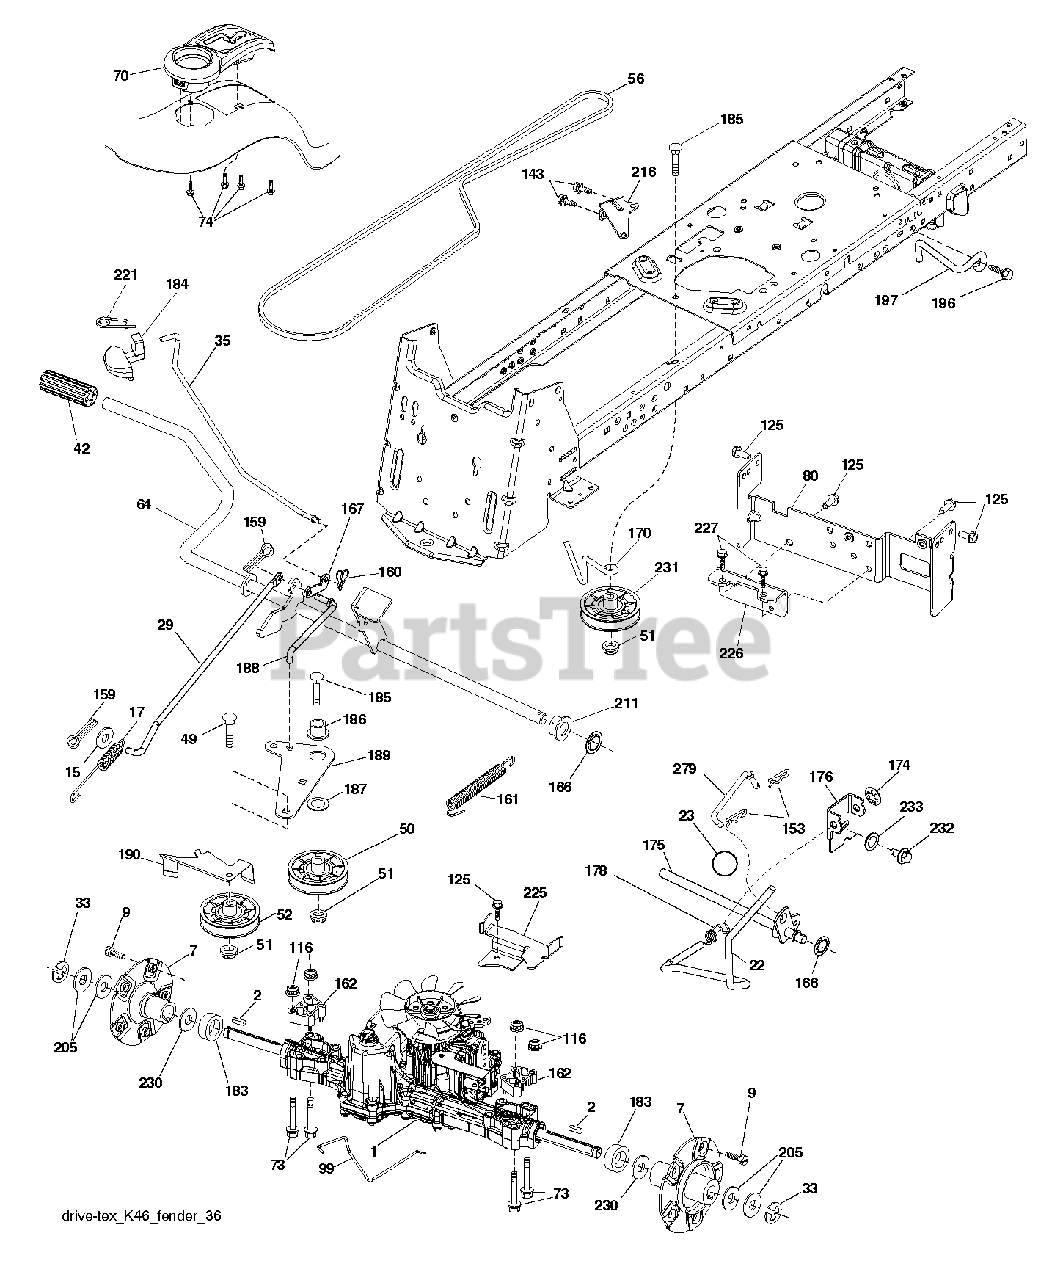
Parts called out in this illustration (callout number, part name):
2	KEY.SQUARE.187X2.500
7	HUB.ASM.WHEEL.REAR.22"
9	HUB BOLT
17	SPRING.BRAKE.K46.GREEN
22	ROD.SHIFT.FENDER.STGT.
23	KNOB.DELUXE.(PISTOL.GRIP).BLAC
29	ROD.BRAKE.K46
33	E-RING LT
35	ROD.BRAKE.PARKING.LT.T
49	BOLT
50	IDLER.FLAT.910.OFFSET
51	NUT LOCK FLG 3/8-16 UNC
52	IDLER.V-GROOVE.910.OFFSET
56	V-BELT.MOWER.92.40.42/K46
64	SHAFT.ASM.PEDAL.BRAKE.
70	PAD.FOOTREST.RH.STGT.BLACK
73	Hex Flange Bolt, 5/16-18 X 3.75
74	SCREW.HI-LO.CONSOLE
80	STRAP.TORQUE.K46.K57R.TT
99	ROD.SPRING.BYPASS.K46.TEX.GT
116	NUT LOCK HEX FLANGE 5/16-18
125	SCREW
143	SCREW LT
159	COTTER PIN
160	RETAINER CLIP
161	SPRING, RETURN LT
162	SPACER.TRANSAXLE.1"
166	NUT.PUSH.625
167	LATCH.BRAKE.SPRING
170	KEEPER.CENTER SPAN.1.688
174	NUT.PUSH.500.2006
175	SHAFT ASM SHIFT
176	ARM.CLEVIS.ROD.SHIFT
178	SPRING.SHIFT.GT2006
183	SPACER.SPLIT.800X.350
184	HANDLE.PARKING.BRAKE.LTTEX.667
186	SPACER.RETAINER
187	WASHER 12/32X2X10GA
188	LINK.CLUTCH.GROUND.DRIVE
189	BELLCRANK.GROUND.DRIVE.TEX.
190	KEEPER.BELLCRANK.DRIVE
196	SCREW 3/8-16X1
197	BRKT.ANIT-ROTATION.CLUTCH
211	BUSHING.SHAFT.BRAKE.HAND
216	BRACKET.PULLEY.IDLER.W/TEX
221	RETAINER.SPRING.CLIP.H
225	KEEPER.BELT.TRANSAXLE.K46
226	BRKT.MOUNT.TORQUE.K46.
227	Screw, Lt
230	WASHER.HARDENED
231	IDLER.V-GROOVE.1.688.OFFSET
232	BOLT FIN HEX 7/16-14 X 1
233	WASHER SERRATED
279	LINK.SHIFT.T/A.K46.FEND.TX
